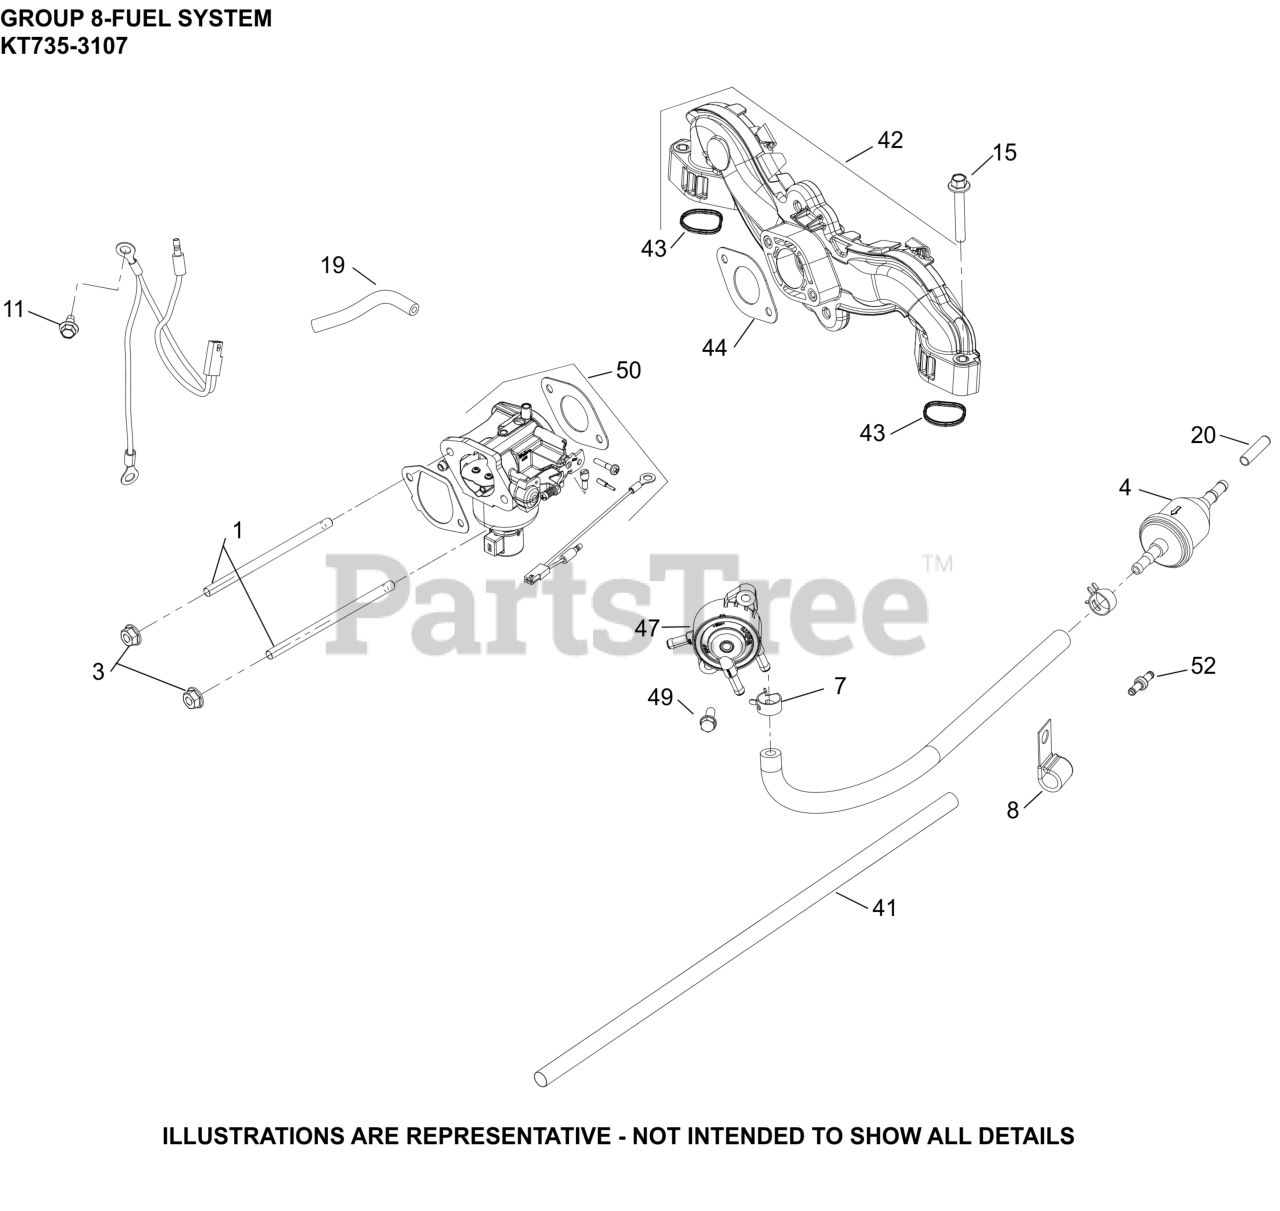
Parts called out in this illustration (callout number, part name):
3	NUT, FLG M6X1.0
4	FILTER,FUEL 51 MICRON (FUEL PUMP)
7	SPRING CLAMP, HOSE
8	CLIP, CABLE (KM)
11	SCREW, THREAD FORMING
15	SCREW, FLG M6X1.0X40
19	HOSE, EVAPORATIVE 20"- (#24326143S)
20	CAP, MASKING
41	SLEEVE, ANTI-ABRASION
42	INTAKE MANIFOLD W/GASKETS
43	O-RING, INTAKE PORT
44	GASKET, CARBURETOR (PIM, CV)
47	PUMP, FUEL (PULSE)
49	SCREW, HEX HEAD
50	KIT, CARBURETOR COMPLETE
52	FITTING, FUEL SYSTEM
NI	KIT,REPAIR OVERHAUL(WALBRO)
NI	KIT,BOWL O-RING(WALBRO)
NI	KIT, HIGH ALT (4000-8000 FT)WALBRO)
NI	KIT,SOLENOID REPAIR(WALBRO)
NI	KIT,REPAIR FLOAT(WALBRO)
